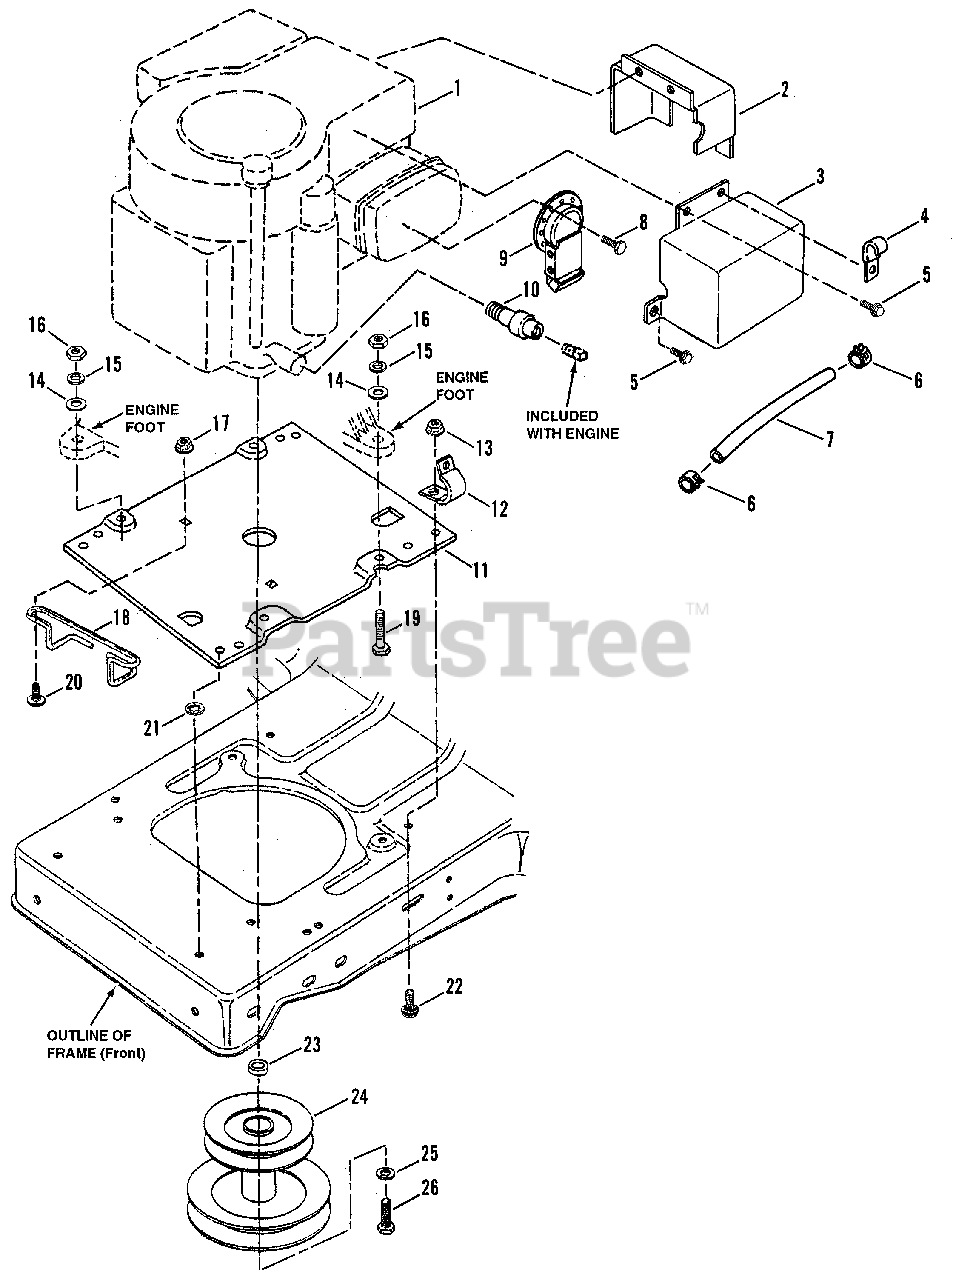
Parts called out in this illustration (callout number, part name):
1	* ENGINE, B&S, 14 HP OHV Mod. 287707-0101-01 (42" Model)
2	HEAT SHIELD, Valve Cover
3	HEAT SHIELD, Muffler
4	CLIP, "J" Type
5	BOLT, 1/4-20 x 1/2" Hex Flange Lock
6	CLAMP, Fuel Line
7	LINE, Fuel, 16"
8	SCREW, #8-18 x 1/2" Hex Flange Lock
9	EXTENSION, Muffler
9	EXTENSION, Muffler (Longer)
10	EXTENSION, Oil Drain (Short)
11	SUB-PLATE, Engine
12	CLIP, Harness
13	NUT, 5/16-18 Hex Fig. Lk.
14	WASHER, 5/16 Flat
15	WASHER, 5/16 Split Lock
16	NUT, 5/16-18 Hex
17	NUT, 1/4-20 Hex Fig. Lk.
18	GUIDE, Belt
19	SCREW, 5/16-18 x 1 1/2" Hx. Hd.
20	BOLT, 1/4-20 x 5/8" Short Neck Carriage, Grade 5
21	WASHER, 5/16 Int. Tooth Lock
22	BOLT, 5/16-18 x 1" Hex Flange Lock
24	PULLEY ASSEMBLY
25	WASHER, 7/16 Split Lock
26	BOLT, 7/16-20 x 1 1/2", Grade 5
